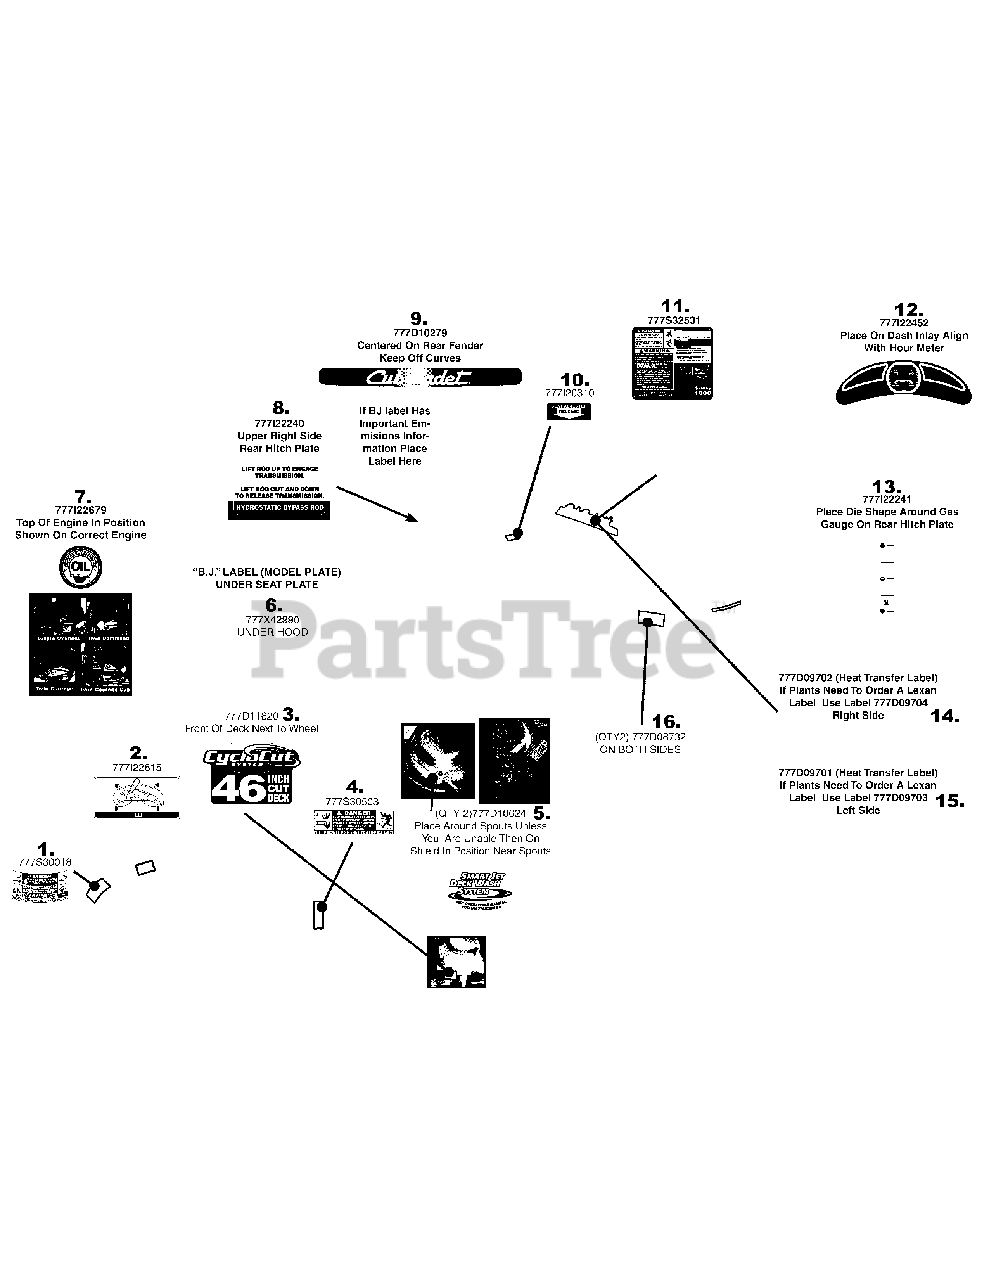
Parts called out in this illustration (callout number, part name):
1	LABEL-DECK SAFETY
2	LABEL-BELT ROUTE
3	LABEL-CYCLO CUT 46" BLUE
4	LABEL-DANGER CHUTE
5	LABEL-RIDER:DECK WASH CUB
6	LABEL-PARTS LIST LT1046 1000 SER
7	LABEL-CHECK ENG OIL
8	LABEL-HYDRO ENGAGE
9	LABEL-REAR FENDER
10	LABEL-SEAT ADJUSTE
11	LABEL-FRAME COVER
12	LABEL-DASH PANEL
13	LABEL-FUEL LEVEL
14	LABEL-RGT SIDE HOOD
15	LABEL-LFT SIDE HOOD
16	LABEL-MODEL LT1046
